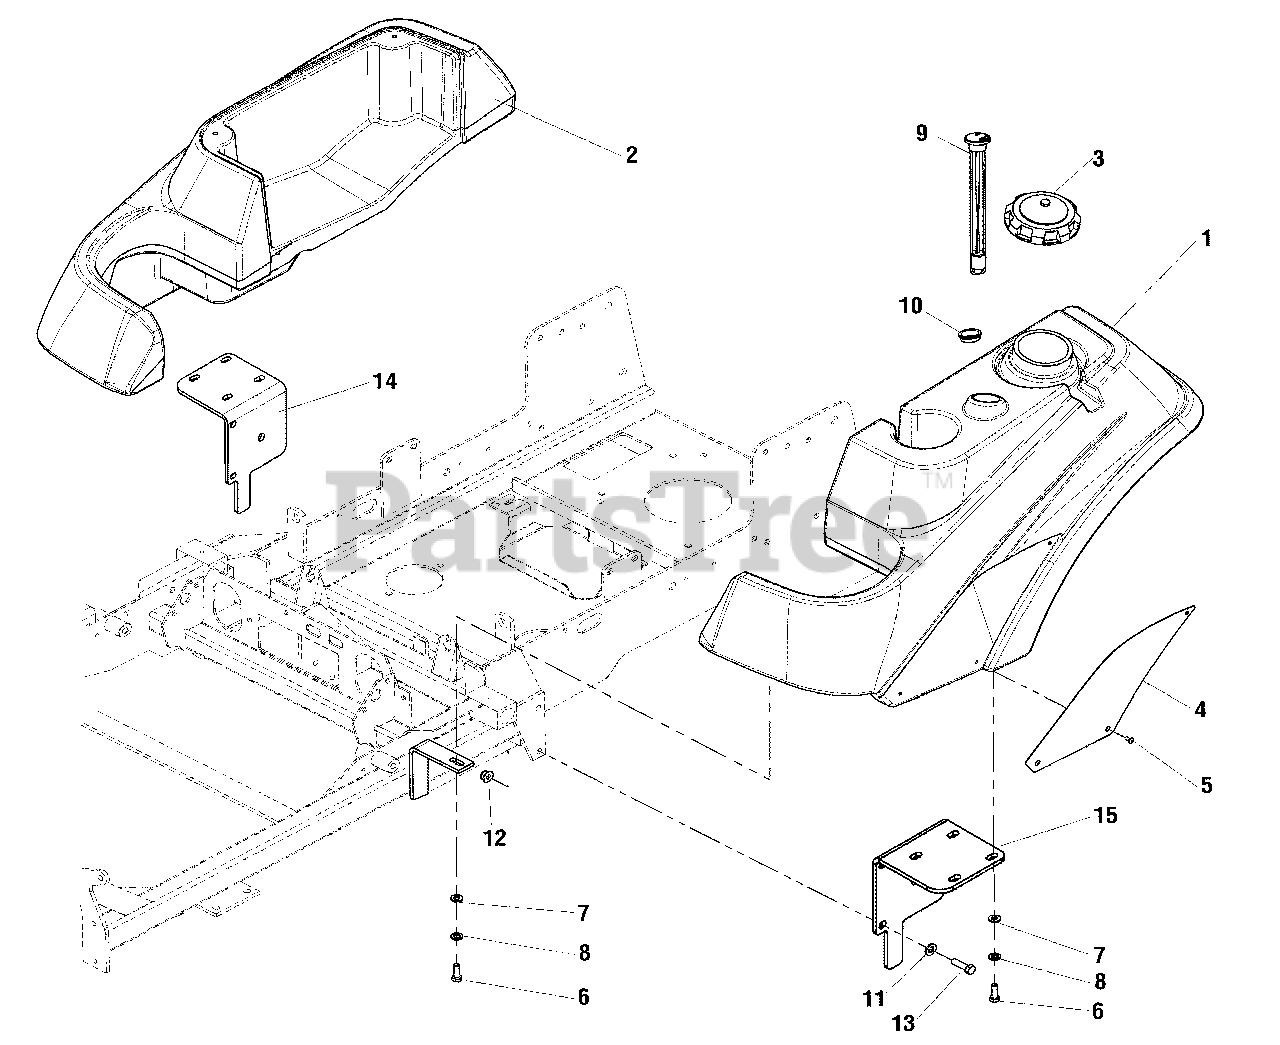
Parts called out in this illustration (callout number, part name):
2	TANK, FENDER, CITATION/ZT4000 - RH
4	BADGE, IS1500Z
5	SCREW, #10-24 X 3/8 ALLEN BHBZ
6	BOLT, 5/16-18 X 1 GD5 YZ
7	WASHER, 5/16 LOCK YZ
8	WASHER, 5/16" SAE
9	GAUGE, FUEL LEVEL
10	GROMMET
11	WASHER, 3/8 SAE
12	NUT, 3/8-16 HEX NYLOCK FLANGE
13	BOLT, 3/8-16 X 1 GD5 YZ
14	WELD, TANK MOUNT - RH - BLK
15	WELD, TANK MOUNT - LH - BLK
